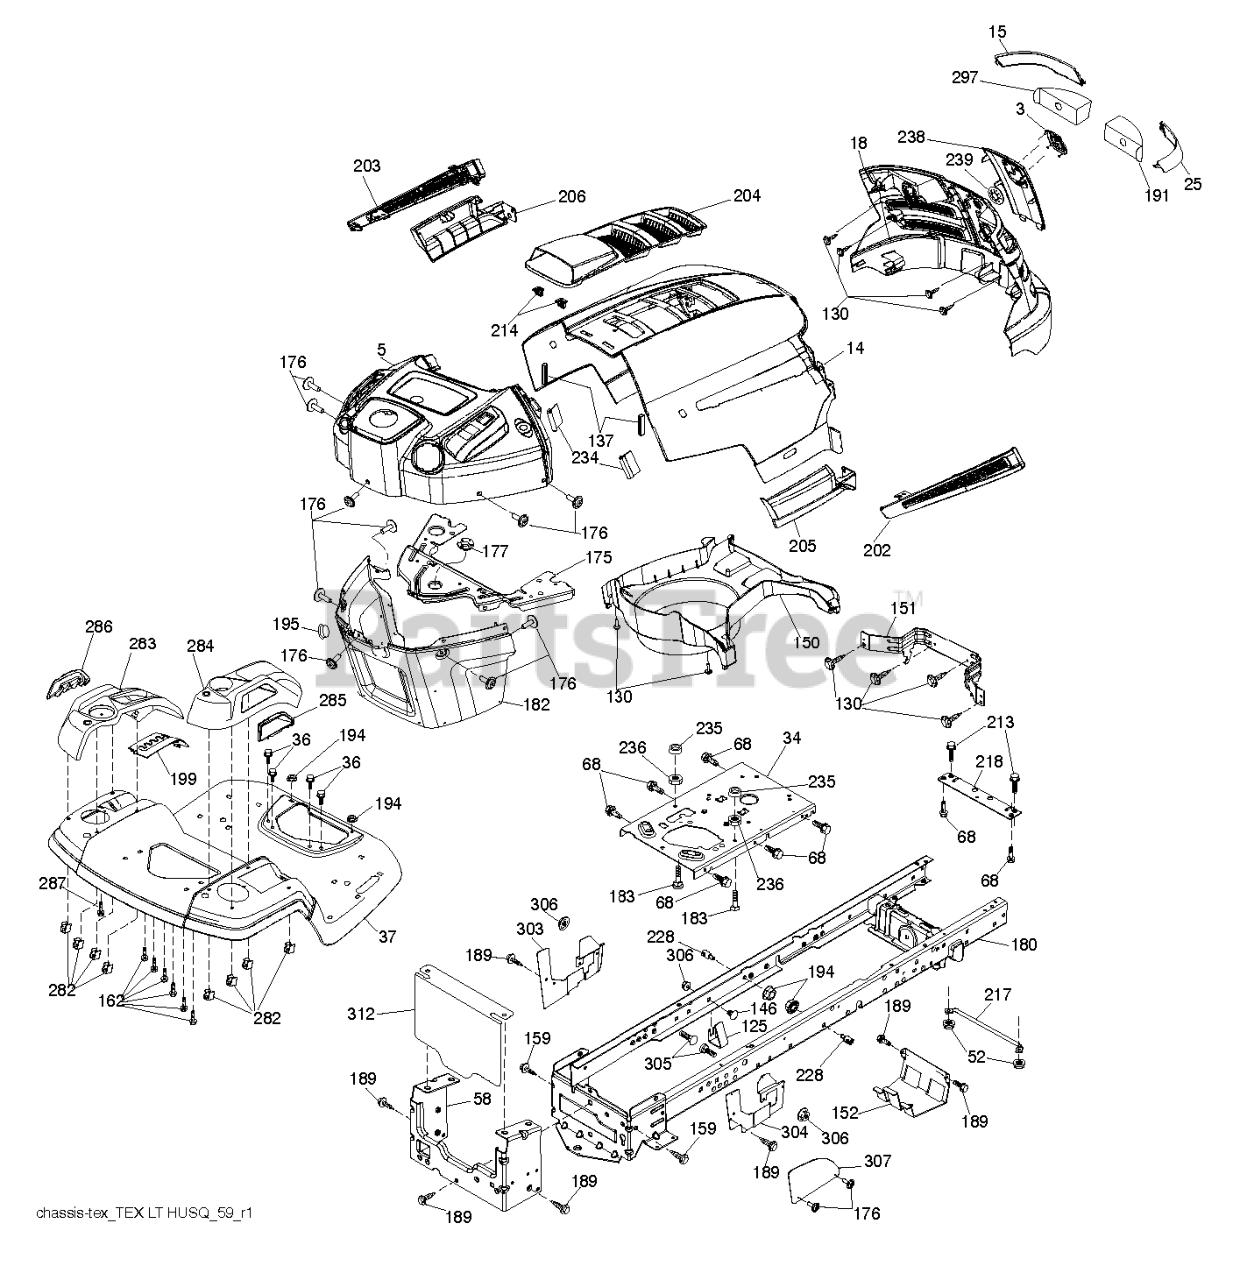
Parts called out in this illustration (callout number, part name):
3	LOGO.HUSQ.GT.LT.CROWN.H
5	SUBASM.DASH.UPPER.HLT.498
14	HOOD.HUSQVARNA.LT.ORANGE
15	LENS.HUSQVARNA LT.RH
18	GRILLE.SVC.HUSQVARNA.GREY
25	LENS.HUSQVARNA LT.RH
34	PLATE PLATE ENGINE
36	SCREW 5/16"
37	FENDER.TLT.FS.W/CUPHLD.ORANGE
52	LOCKNUT
58	DRAWBAR UPPER 2PC SMALL FENDER
68	Screw 5/16-18 x 1/2 Hex, Self Tapping 5/16-18 x 1/2
125	CLIP.FUEL.LINE
130	SCREW.#10 X 0.750.BOS
137	BUMPER DASH
146	BOLT.RDHD.SHT.SQNK.3/8-16X5/8
151	BRACKET PIVOT
152	SHIELD.BROWNING.W/TEX
159	SCREW, 3/8-16X3/4
162	SCREW.HI-LO.CONSOLE
175	CROSSMEMBER
176	SCREW.#10-24X5/8.RN.QU
177	BUSHING STEERING
180	CHASS.WLDMNT.TL.12GA/2P.48/54
182	DASH.LOWER.PREDATOR LT
183	BOLT.5/16-18X1-1/4 FULL THD
189	SCREW
191	INSERT.REFLECTIVE.RH.
194	NUT LOCK HEX FLANGE 5/16-18
195	PLUG.TEX.DASH.SVC.MINDER.GREY
199	PLATE.DECK.LIFT.HUSQ.LT
202	VENT.SIDE.HUSQVARNA.LT.RT
203	VENT.SIDE.HUSQVARNA.LT.LFT
204	SUBASM.TOP.VENT.HUSQ.LT
205	SKIRT.SIDE.HUSQVARNA.LT.RT
206	SKIRT.SIDE.HUSQVARNA.LT.LEFT
213	BOLT
214	CLIP.RETAINER.TINNER.
217	ROD.PIVOT.HOOD
218	X-PIECE.HOOD.STOP.NON/
228	STUD.FASTNER.W/ANTI-ROTATE
234	BUMPER.HOOD.TEX.HUSQVARNA
235	SPACER FENDER
236	NUT.CENTERLOCK.5/16-
238	TRIM.HUSQ LT.668
282	CLIP.RETAINER.CONSOLE.LT.HUSQ
283	CONSOLE.ASM.LFT.RSF.HUSQ.LT
284	CONSOLE CONSOLE.HUSQ.SHIFT.HYD
285	CONSOLE INSERT RH
286	CONSOLE.INSRT.LH.HUSQ.LT.BLACK
287	SCREW 1/4X20
297	INSERT REFLECTIVE
303	SHIELD CHASSIS LEFT
304	SHIELD CHASSIS RIGHT
305	BOLT
306	NUT LOCK FLG 3/8-16 UNC
307	SHIELD UPPER PEDAL
312	SHIELD.PNT.DRAWBAR.FRENCH
